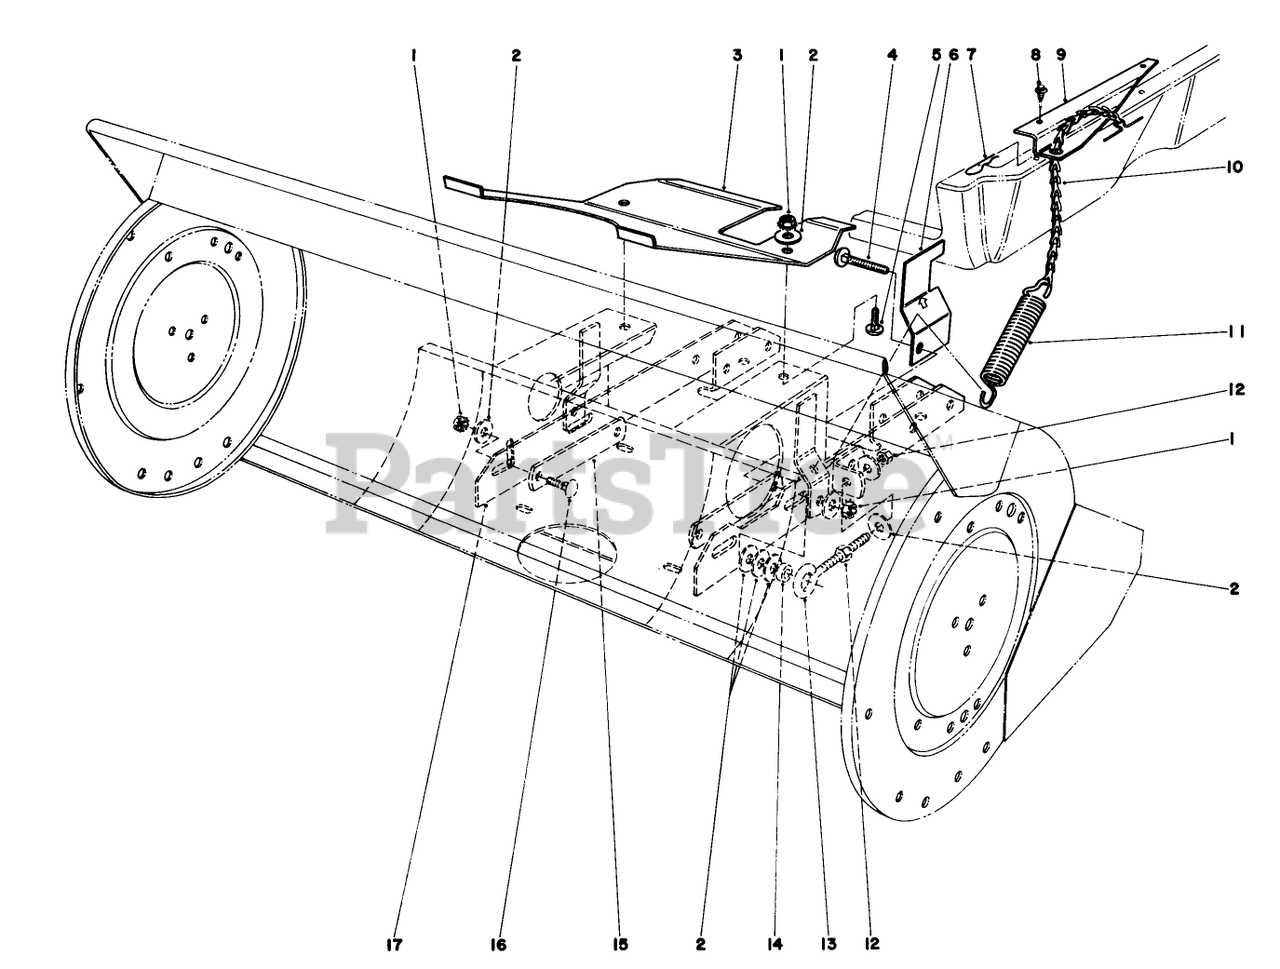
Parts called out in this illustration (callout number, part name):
1	NUT-KEPS
2	WASHER-FLAT
4	SCREW-CARR
5	SCREW-CARR
7	PIN-HAIR
8	SCREW-HWHTF
12	NUT-HEX
16	BOLT-CARR
